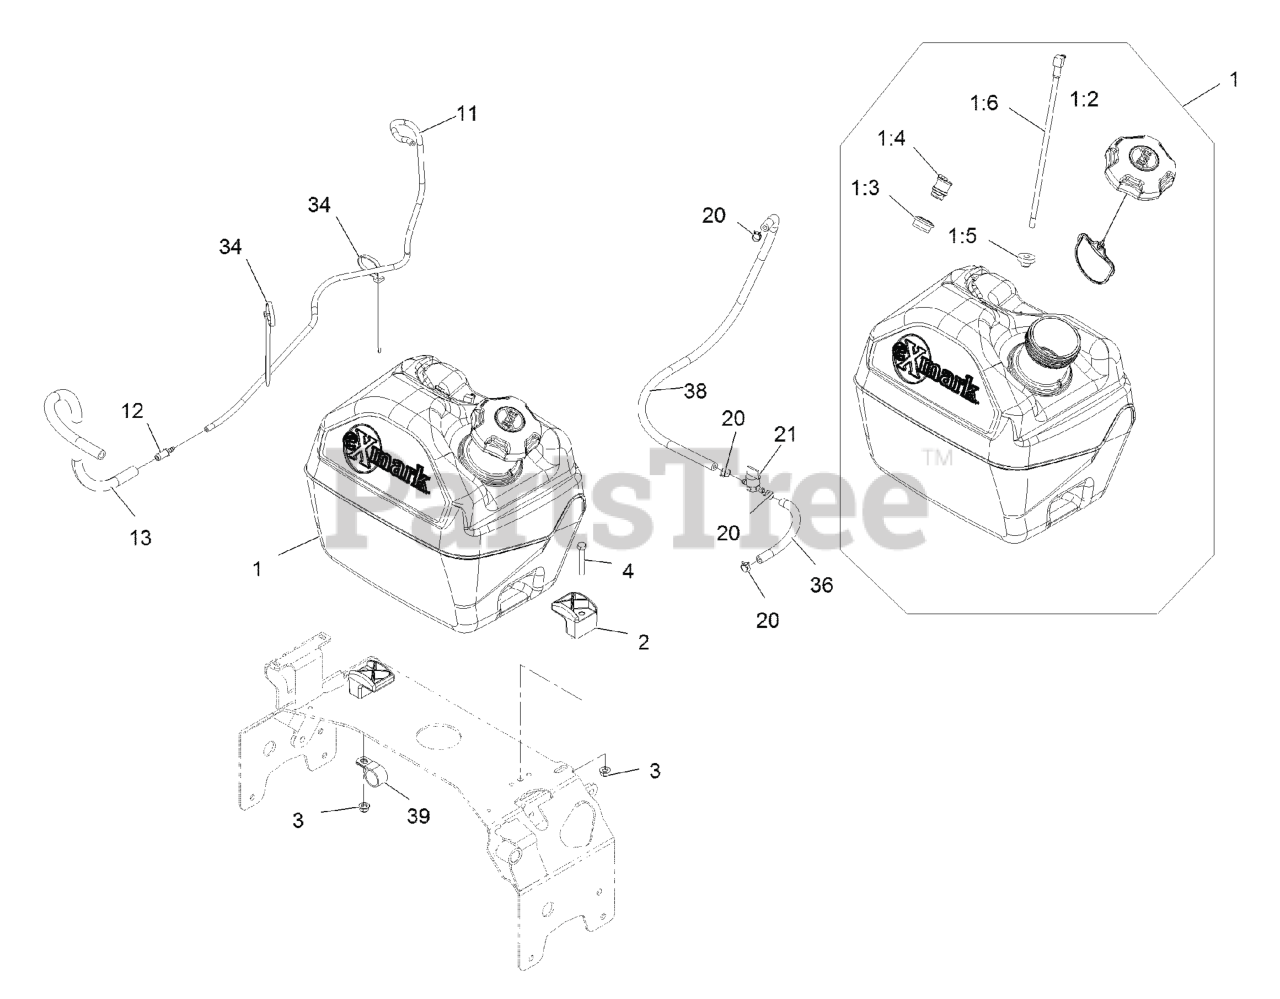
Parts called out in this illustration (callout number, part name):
1	ASM, FUEL TANK 5 GAL
1:2	CAP-FUEL, RATCHETING
1:3	GROMMET
1:4	VALVE-VENT, FUEL
1:5	BUSHING
3	NUT-HF, NI
4	SCREW-HH
11	HOSE, EMISSIONS
12	FITTING-STRAIGHT
13	HOSE-FUEL
20	CLAMP-HOSE
21	VALVE-FUEL
34	TIE-PLASTIC
36	HOSE-FUEL
38	HOSE-FUEL
39	CLIP-LOOM
